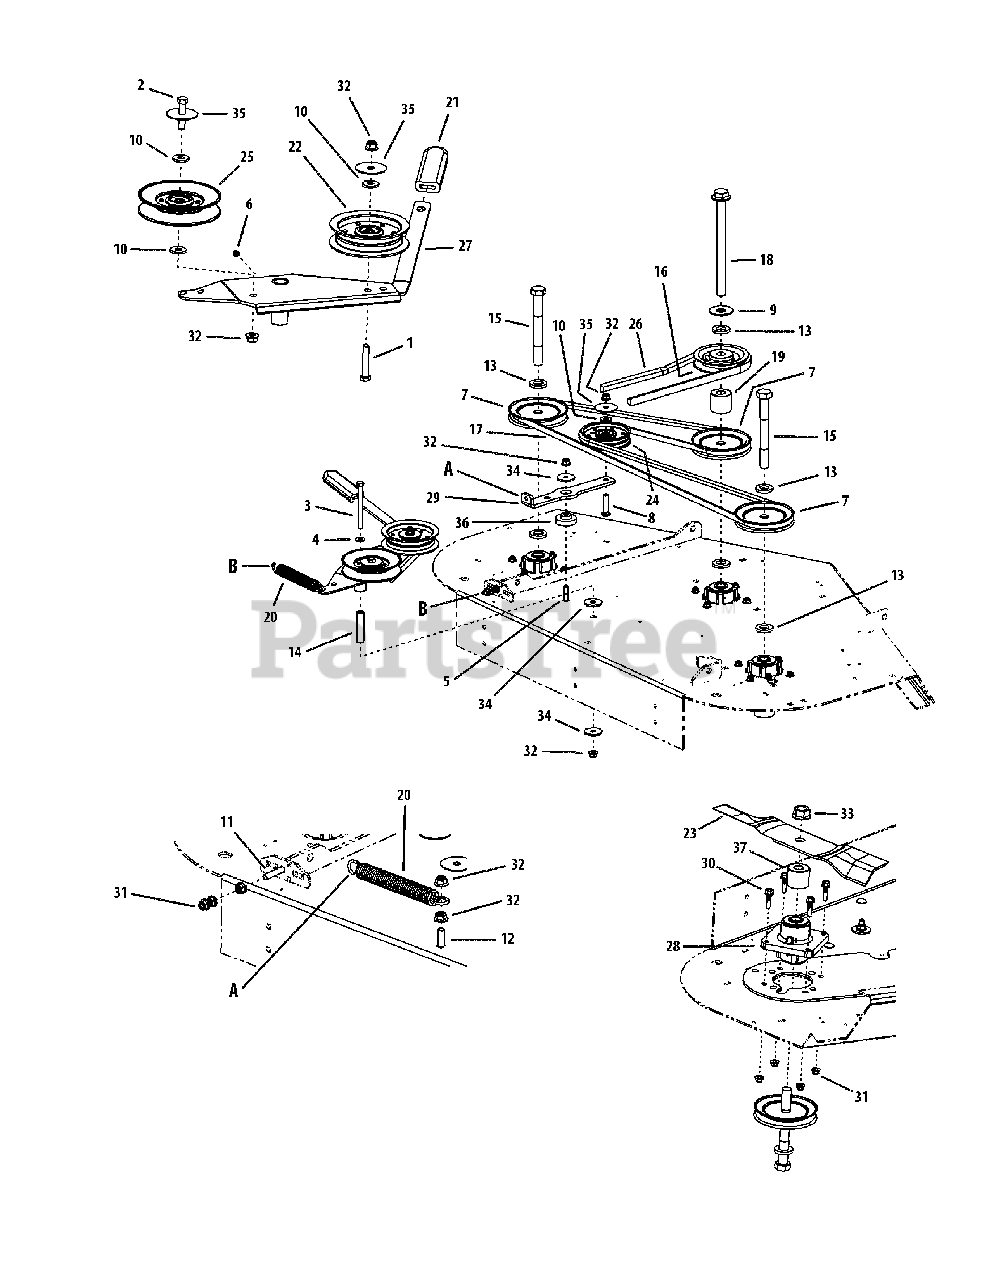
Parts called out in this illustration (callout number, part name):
1	Hex Cap Screw, 3/8-16 x 2.00
2	Hex Cap Screw, 3/8-16 x 1-3/4
3	Hex Cap Screw, 3/8-16, 4.00
4	Washer, 3/8
5	Carriage Bolt, 3/8-16 x 1-1/2
6	Grease Fitting, 1/4-28 x 3/16
7	V-Pulley 4.90 OD
8	Carriage Bolt, 3/8-16, 1.75
9	Flat Washer, .781 ID 2.00 OD, .105
10	Flat Washer, .406 ID, 1.0 OD, .105
11	Carriage Bolt, 5/16-18 x 1.75
12	Carriage Bolt, 3/8-16 x 1.25
13	Spacer .812 ID x .268 LG
14	Spacer, .39 ID x .625 OD x 2.75
15	Hex Cap Screw, 3/4-16 x 6.50
16	V-Pulley 5.25 OD
17	V-Belt, A Section x 105.3
18	Hex Cap Screw, 3/4-16, 9.00
19	Spacer, .76 ID x 1.75 OD x 1.60
20	Extension Spring, .94 OD x 7.57 LG
21	Idler Tension Handle Grip
22	Idler Pulley, 4.06 OD w/Deep Flange
23	Blade, 17.0, Hi-Lift, 0.756 ID
24	Idler Pulley, 4.06 Dia.
25	Idler Pulley, 5.06 Dia.
26	V-Belt, B Section, 87.2
27	Idler Arm Assembly
27	Bearing
28	Aluminum Spindle Assembly
30	Bolt, 5/16-18 x 1.25
31	Nut, Nylon Insert, 5/16-18
32	Nut, Nylon Insert, 3/8-16
33	Nut, 3/4-16, Flangelock
34	Washer, .390 x 1.50 x .134
35	Washer, .406 x 1.92 x .060
36	Shoulder Spacer, .854 x .280
37	Spacer, .76 ID x 1.75 OD x 1.50
